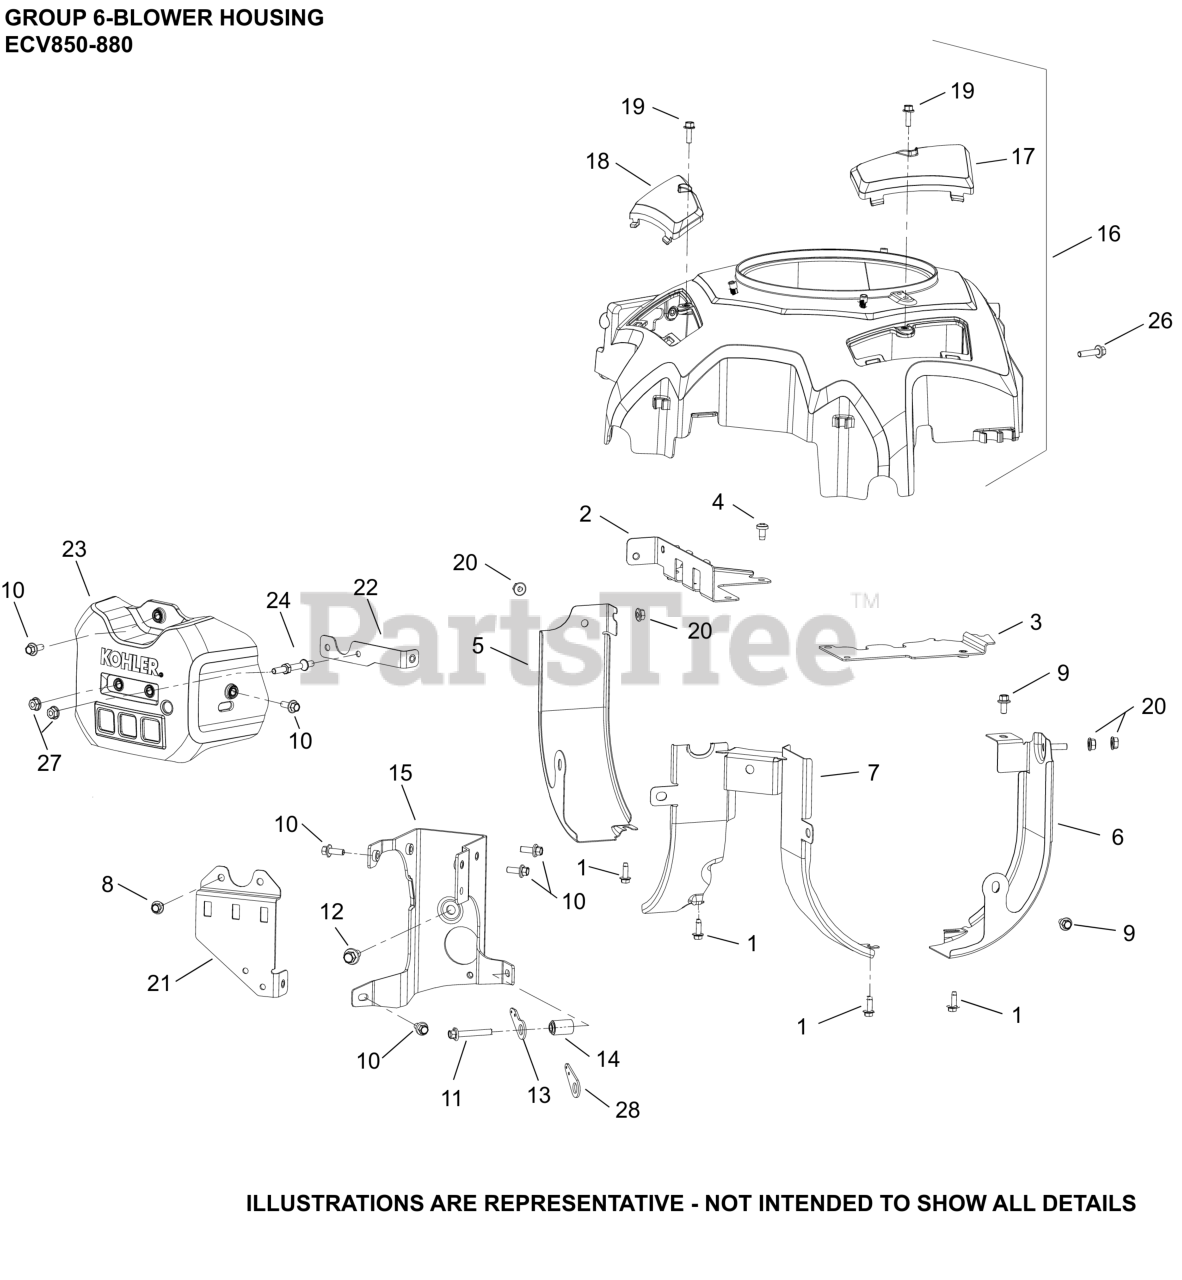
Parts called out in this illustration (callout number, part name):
1	SCREW, THREAD FORMING
1	SCREW,THREAD FORMING
2	BAFFLE, CRANKCASE #1 CYLINDER
3	BAFFLE, CRANKCASE #2 CYLINDER
5	BAFFLE, BARREL #1 CYLINDER
6	BAFFLE, BARREL #2 CYLINDER
7	BAFFLE, VALLEY ASSEMBLY
8	SCREW, FLG M6X1.0X10
9	SCREW, FLG M6X1.0X12
10	SCREW, FLG M6X1.0X16
11	SCREW, FLG M6X1.0X40
12	SCREW, FLG 8X1.25X16
14	SPACER, STEPPED O.D.
15	BRACKET, THROTTLE BODY
16	KIT, BLOWER HOUSING
17	COVER, CLEAN OUT #2 CYLINDER
18	COVER, CLEAN OUT #1 CYLINDER
19	SCREW, HVY FLG M5X.8X16
21	BRACKET, FUSE HOLDER
22	BRACKET, FUSE COVER
23	COVER, FUSE
24	STUD, BLOWER HOUSING MOUNTING
26	SCREW, HEX FLANGE M6 X 1
